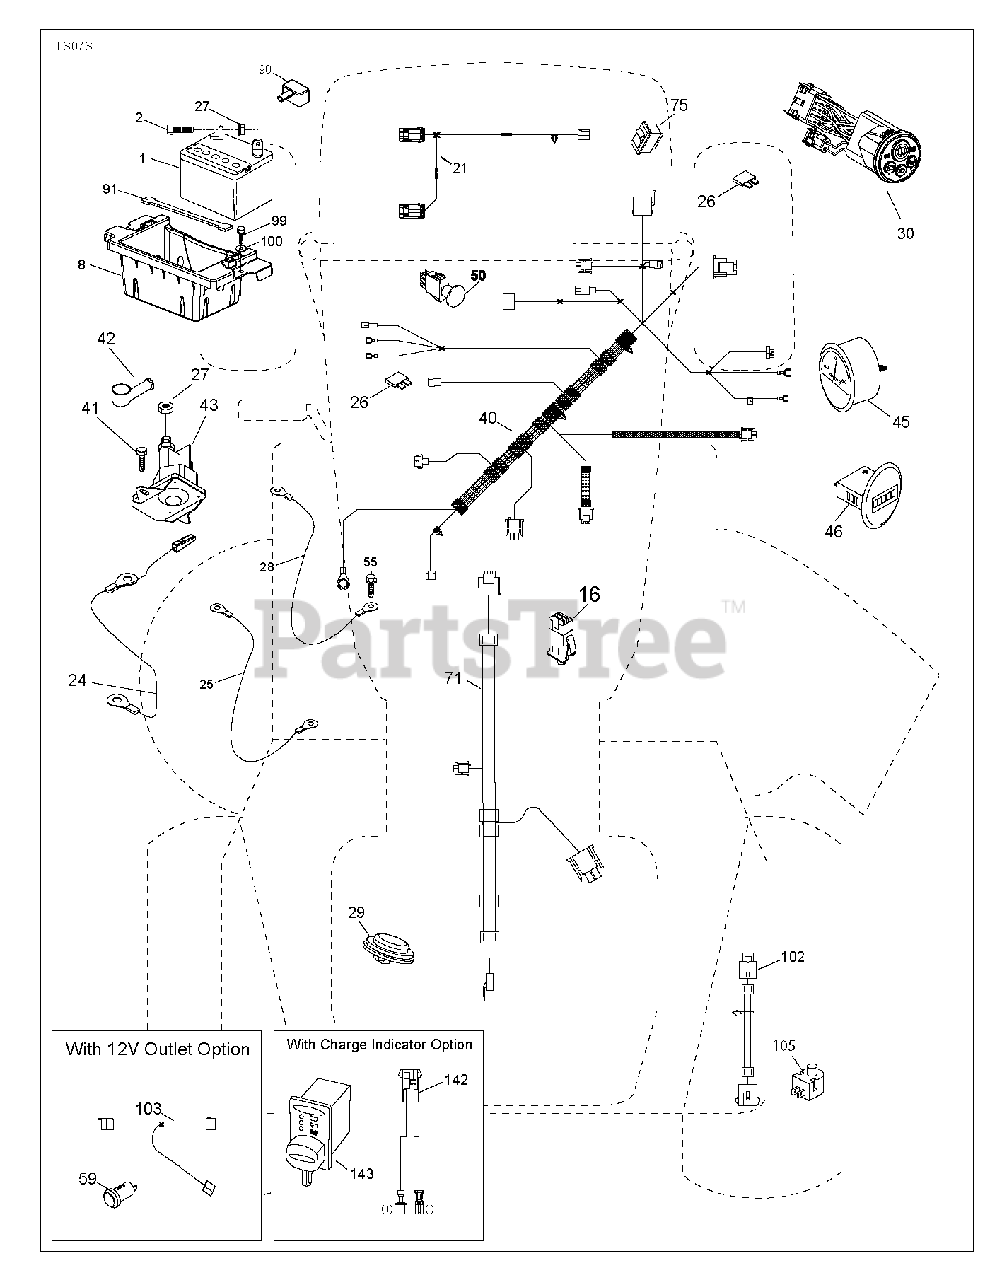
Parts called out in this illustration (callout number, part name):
1	Battery, Dry 30 Amp
2	BOLT.HEX.1/4.X.3/4.DICHROMATE
8	BOX.BATTERY.MOUNT.FRONT.LT
16	SWITCH INTERLOOK PUSH-IN
21	HARNESS LIGHT ASSY TRACTOR,
24	CABLE.BTRY.HARN.POS.LEAD
25	CABLE.STARTER.8GA.17.5
26	FUSE 20AMP
27	NUT
28	CABLE.GROUND.STARTER
29	SWITCH.SEAT.OPC.GRY.BUTTON/CAP
30	SMART SWITCH MY14 TRACTOR
40	HARNESS.DASH.EL.SIS.RND.FBAT
41	SCREW
42	TERMINAL COVER
43	SOLENOID.W/BRASS.PLUNGER
45	AMMETER GAUGE ROUND SNAP-IN
46	HOURMETER.GAUGE.RNK.SNAPIN.LS
50	RB PTO.SWITCH.8 TERMINAL.BLACK
55	SCREW 5/16"
59	OUTLET.12-VOLT
71	HARNES.CHASS.TEX.SIS.FBAT.TWIN
75	SWITCH.ON/OFF.(DIFF.LOCK)
90	COVER.TERMINAL.BATTERY
91	STRAP.BATTERY.MOUNT.FRONT(2 2)
99	SCREW HEXWSHR 1/4-20X3/4
100	WASHER
102	HARNESS PIGTAIL PCH TEX ROS
103	HARNESS.12V.ACC.PLUG.56.SERIES
105	REVERSE SWITCH
142	CHARGE.PORT.PIGTAIL HARNESS
143	CHARGE.PORT
